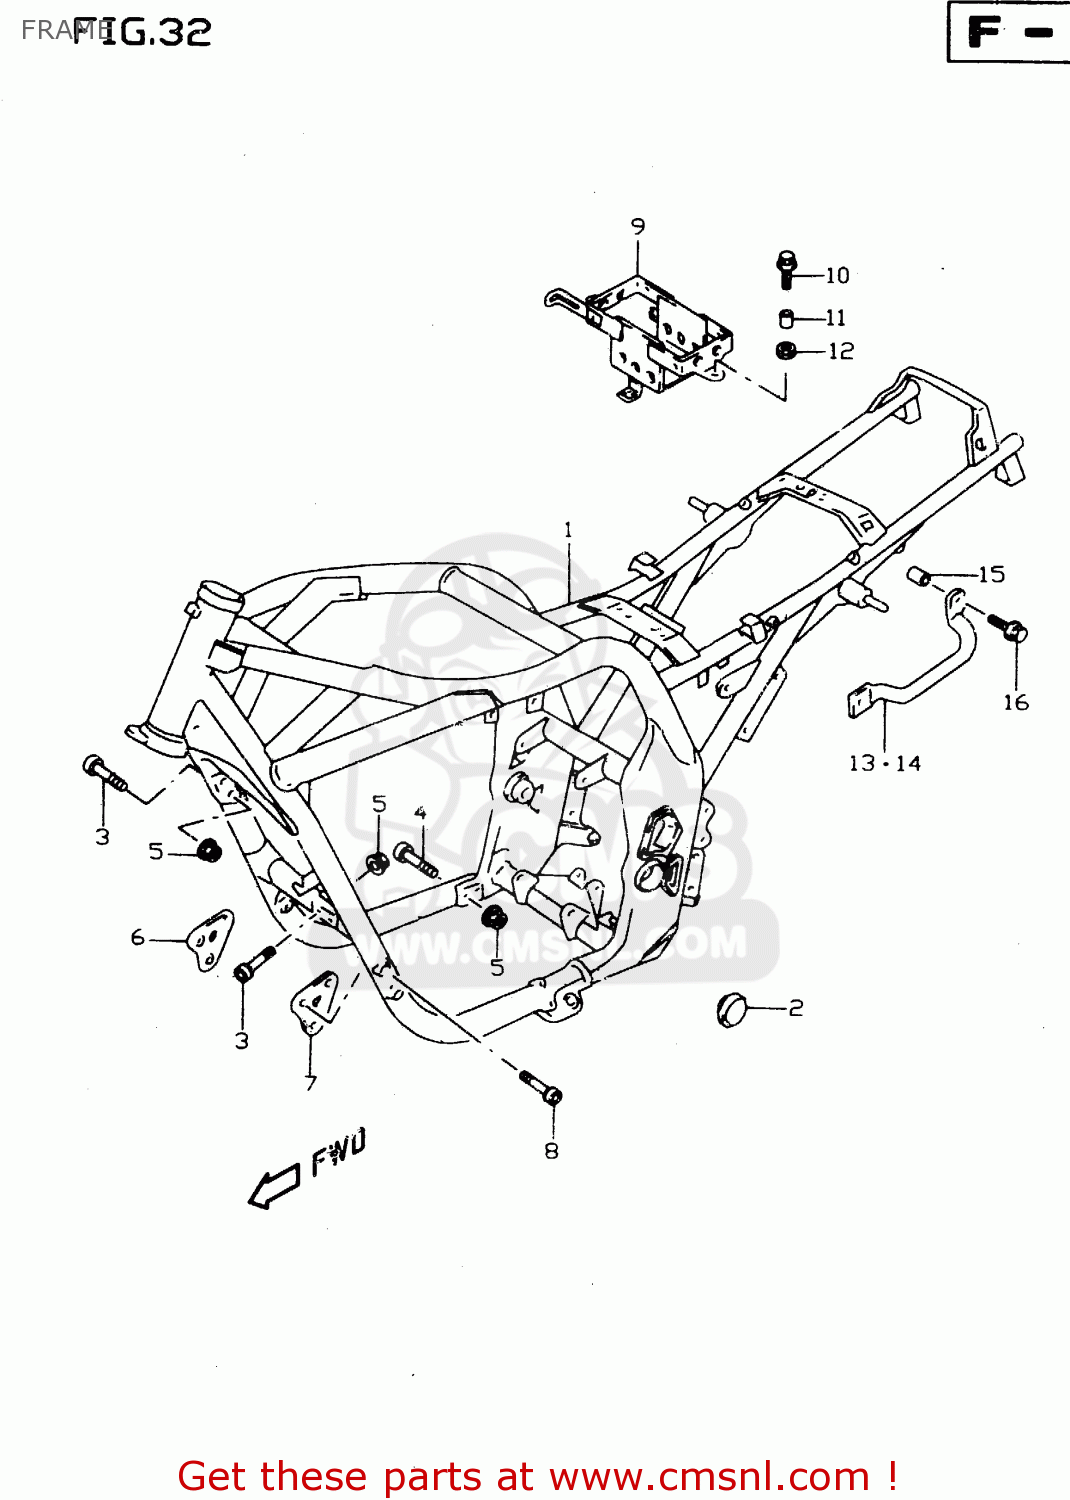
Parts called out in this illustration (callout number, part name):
1	FRAME(BLACK)
2	CAP,FRAME BODY
3	BOLT(10X33)
4	BOLT
5	NUT
6	PLATE,ENG MTG,R(BLACK)
7	PLATE,ENG MTG,L(BLACK)
8	BOLT
9	HOLDER,BATTERY
10	BOLT 6X16
11	SPACER(6.5X9X8.5)
12	CUSHION
13	GRIP,R
14	GRIP,L
15	SPACER(8.2X14X4.5)
16	BOLT
